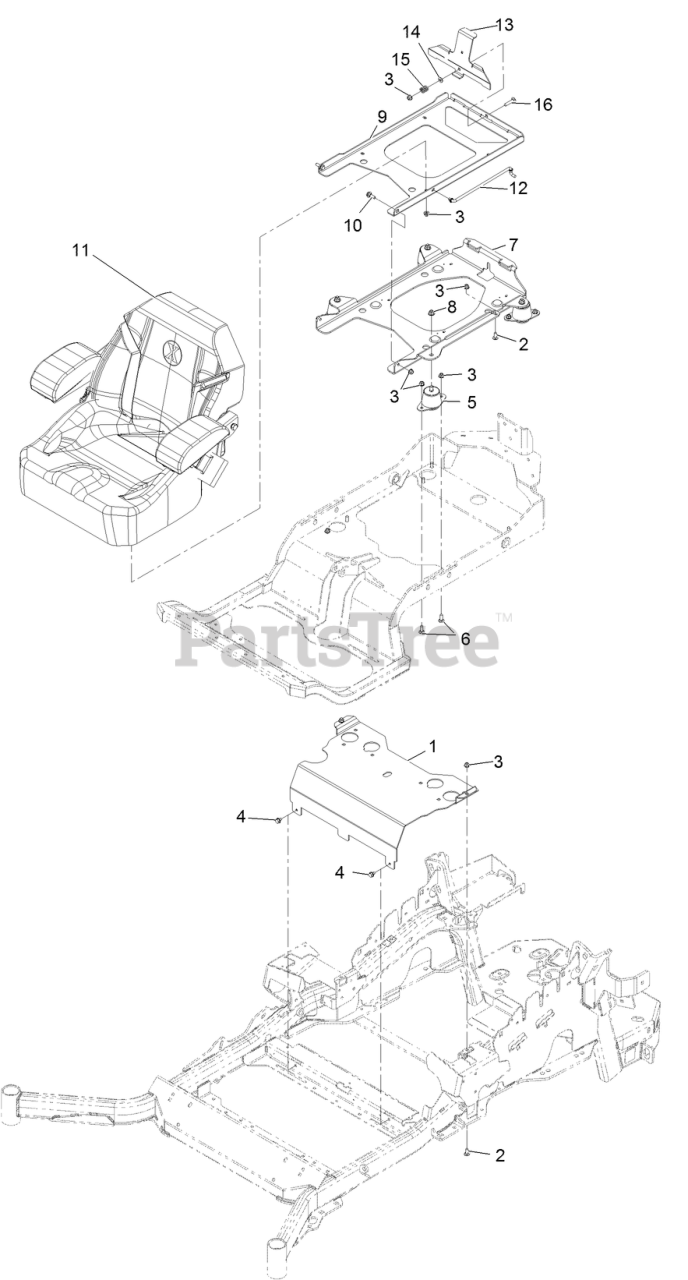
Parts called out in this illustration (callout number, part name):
1	Panel-Front, Seat Mount
2	SCREW-CARR
3	NUT-HF, NI
5	ISOLATOR-SEAT
6	BOLT-CARR
7	PLATE-SUPPORT, ISO SEAT
8	NUT-HF, NI
9	PLATE-FRAME, SEAT
10	SCREW-SHOULDER
11	SEAT-EXMARK STANDARD
12	ROD-PROP
13	PLATE-LATCH,SEAT
14	WASHER-PLAIN
15	SPRING-COMPRESSION
16	BOLT-CARR
